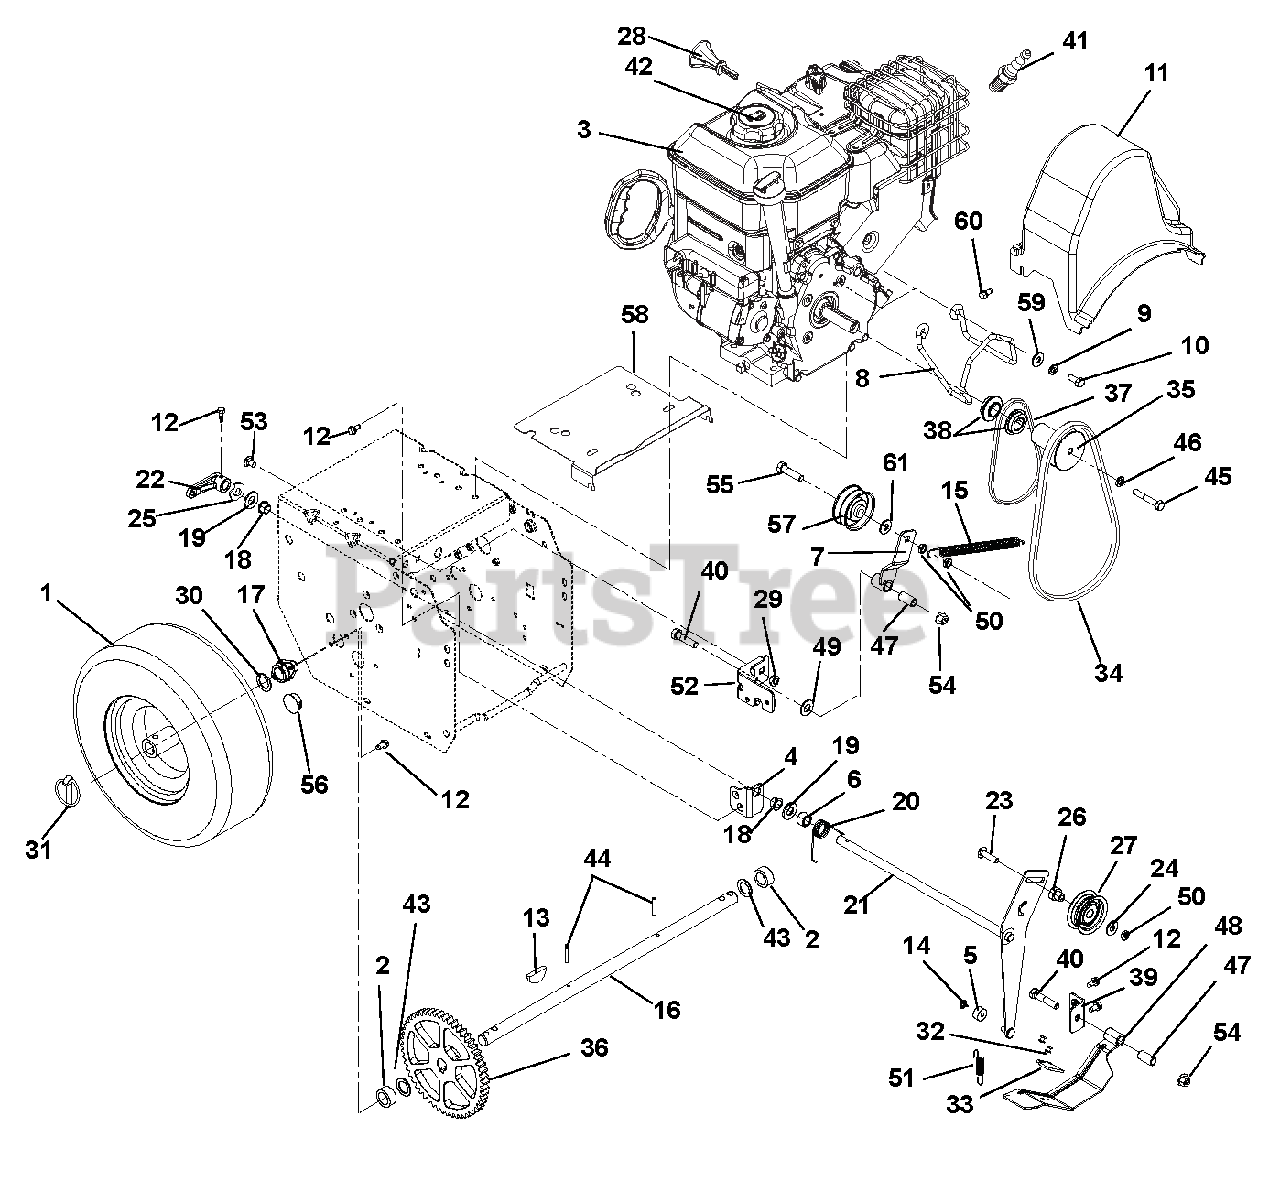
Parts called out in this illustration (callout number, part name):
1	TIRE/WHEEL, RH 4.10-6 PIN K478
2	BSHG-SLV .766 X 1.125 X .500
3	ENGINE, BRIGGS SNOW 900, 120V
4	BRACKET, MOUNT - IDLER ARM
5	BSHG,SLV .265 X .625 X .375
6	BSHG-SLV .510X.751X.475
7	WELDMENT, TRACTION IDLER ARM
8	FINGER, BELT
9	WSHR-LK .312X.097 HVY YWZC
10	BLT-HEX .31-24X.75 YWZC GR5
11	COVER, COMPACT BELT
12	SCR-TAP .25-20X.50 HWH TR YWZ
13	KEY-WDRF .25X.750X.313 SAE91
14	RG-RTNG-EXT .250X.010
15	SG-TENS .062X.56X8.0 WLD 11
16	SHAFT, AXLE
17	BSHG .75X1.125X.65
18	BUSHING, POLYLINER-.50 SPLIT
19	@WSHR-FL-STL.531X1.06X.095YWZC
20	SG-TORS .075 X .955
21	WELDMENT, ATTACHMENT IDLER ARM
22	ARM, CLUTCH - ATTACHMENT
23	BLT-RDHDSQSHNK.31-18X1.13 G5YZ
24	@WSHR-FL-STL.38X.875X.083 YWZC
25	WSHR-WAVE .50X.75X.015 .13FRHT
26	SPCR, BRG .315X.50X.688X.281
27	IDLER
28	KEY, PUSH/PULL BRIGGS
29	@NUT-LK-TOP-FLG .31-18 YWZC
30	WSHR-FL-STL.754X1.125X.062YWZC
31	PIN-LOK .31X1.75
32	RVT-POP .187 YZ
33	PAD, BRAKE
34	V-BELT, HA-RAW EDGE
35	SHEAVE, AUGER - COMPACT
36	SPUR GEAR, 54T .75ID X 6.75PD
37	V-BELT, 3L-WRAPPED
38	TRACTION SHEAVE HALF
39	BRACKET, MOUNT - BRAKE
40	@BLT-HEX .38-16X1.75 GR5 YWZC
41	PLUG, SPARK
42	CAP, FUEL - BRIGGS & STRATTON
43	WSHR-FL-STL.754X1.125X.062YWZC
44	PIN-ROLL .188X1.25
45	@BLT-HEX .31-24X1.75 GR5 YWZC
46	WSHR-LK .312X.097 HVY YWZC
47	BSHG-SLV .385X.500X1.045
48	BRAKE ARM W/PAD
49	@WSHR-FL-STL.406X.812X.065 YWZ
50	@NUT-LK-CTR-JAM .31-18 YWZC
51	SPRING-EXT .437 X .438 X 2.64
52	WELDMENT, FRAME BRACKET
53	@BLT-RHDSSQNK .31-18X.62 G5YZ
54	@NUT-LK-TOP-FLG .38-16 YWZC
55	@BLT-HEX .31-18X1.75 GR5 YWZC
56	PLUG, HOLE - 1.00" FLEXTEMP
57	IDLER,1.875" OD
58	BAFFLE,ENGINE,SMALL BLOCK
59	@WSHR-FL-STL.344X.688X.065YWZC
60	SCR-TAP .25-20X.50 LGHWH TR YZ
61	WSHR-FL-STL .344X1.125X.135
